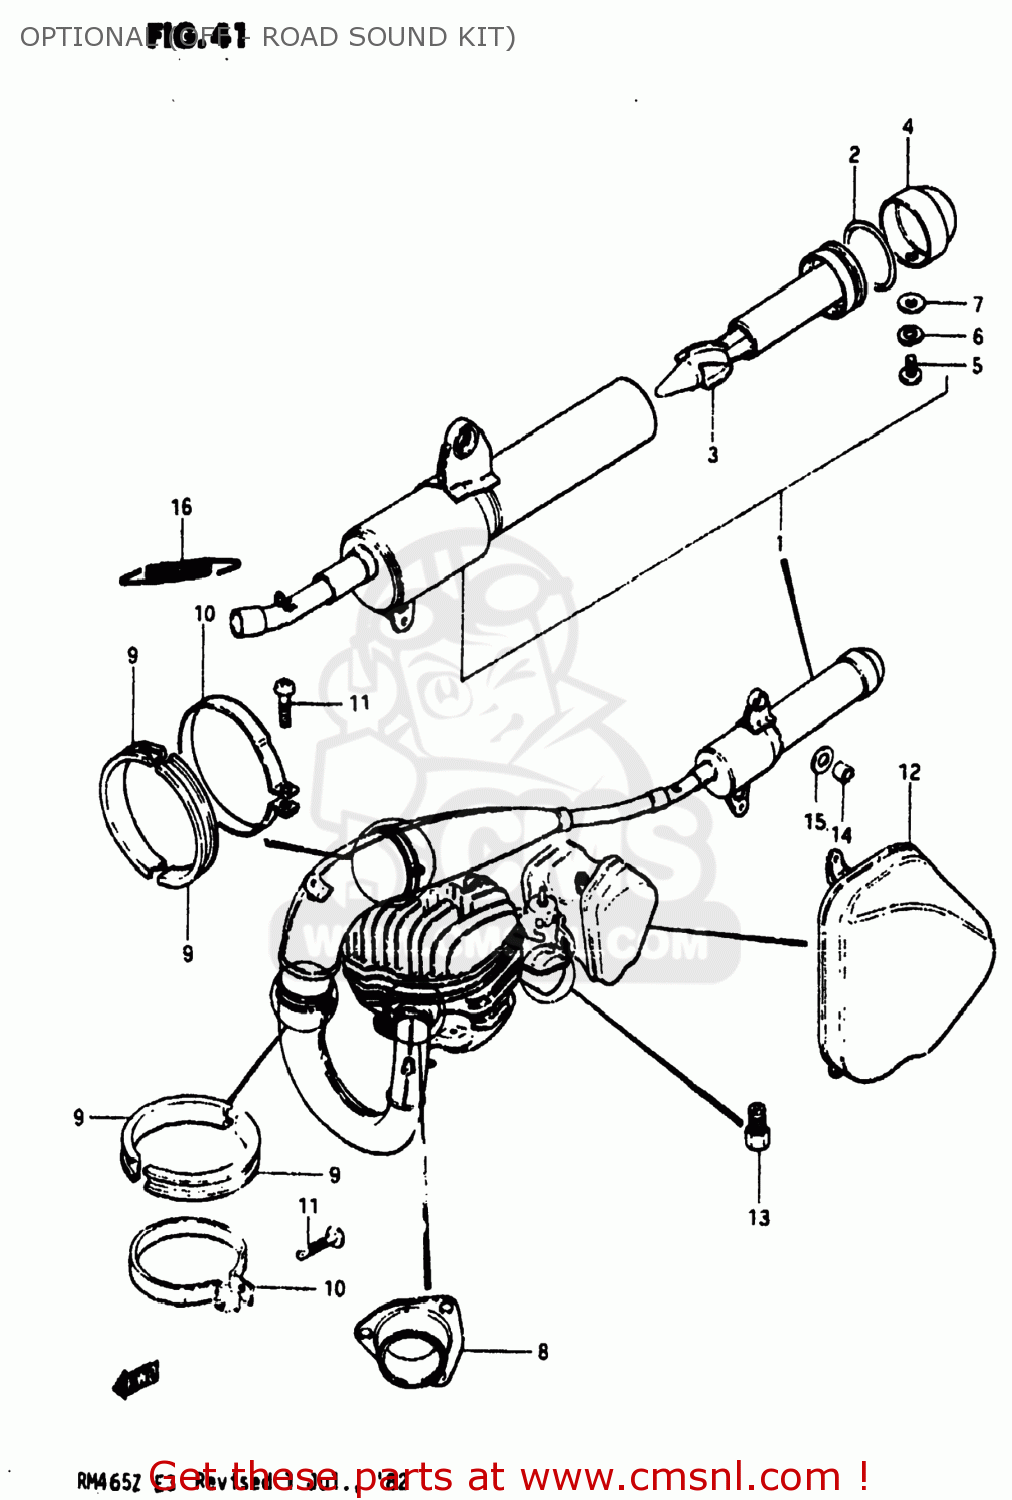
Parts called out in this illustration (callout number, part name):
0	OFF-ROAD SOUND KIT
1	MUFFLER ASSEMBLY
2	O-RING (D:3.5 ID:54.4)
3	TUBE,MUFFLER CLEAN OUT
4	COVER,SECOND MUFFLER TAIL
5	SCREW(6X8)
6	LOCK WASHER
7	WASHER
8	FLANGE,EXHAUST PIPE
9	BODY,MUFFLER
10	CLAMP
11	SCREW
12	CAP,AIR CLEANER
13	JET
14	SPACER
15	GASKET
16	SPRING
